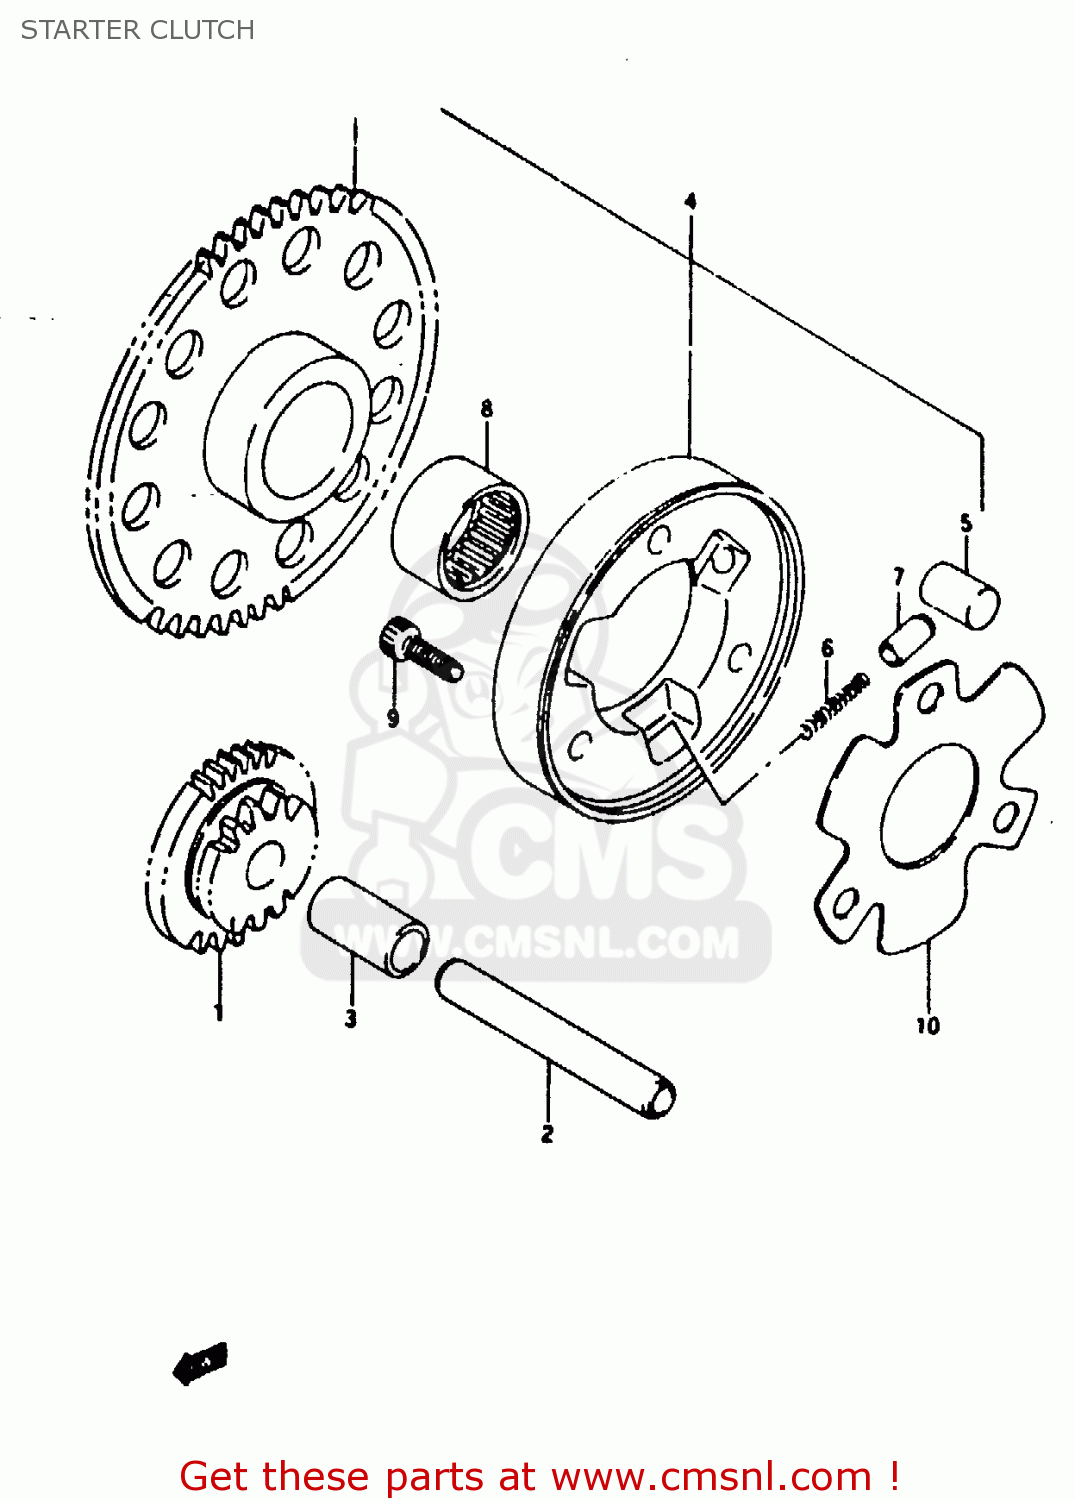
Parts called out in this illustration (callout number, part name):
1	GEAR, STARTER IDLE
2	PIN
3	SPACER
4	CLUTCH SET, STARTER
5	ROLLER(10X11)
6	SPRING
7	PIECE,STARTER CLUTCH PUSH
8	BEARING(22X28X16)
9	BOLT,OIL FILLE
10	SHIM,STARTER CLUTCH HUB
